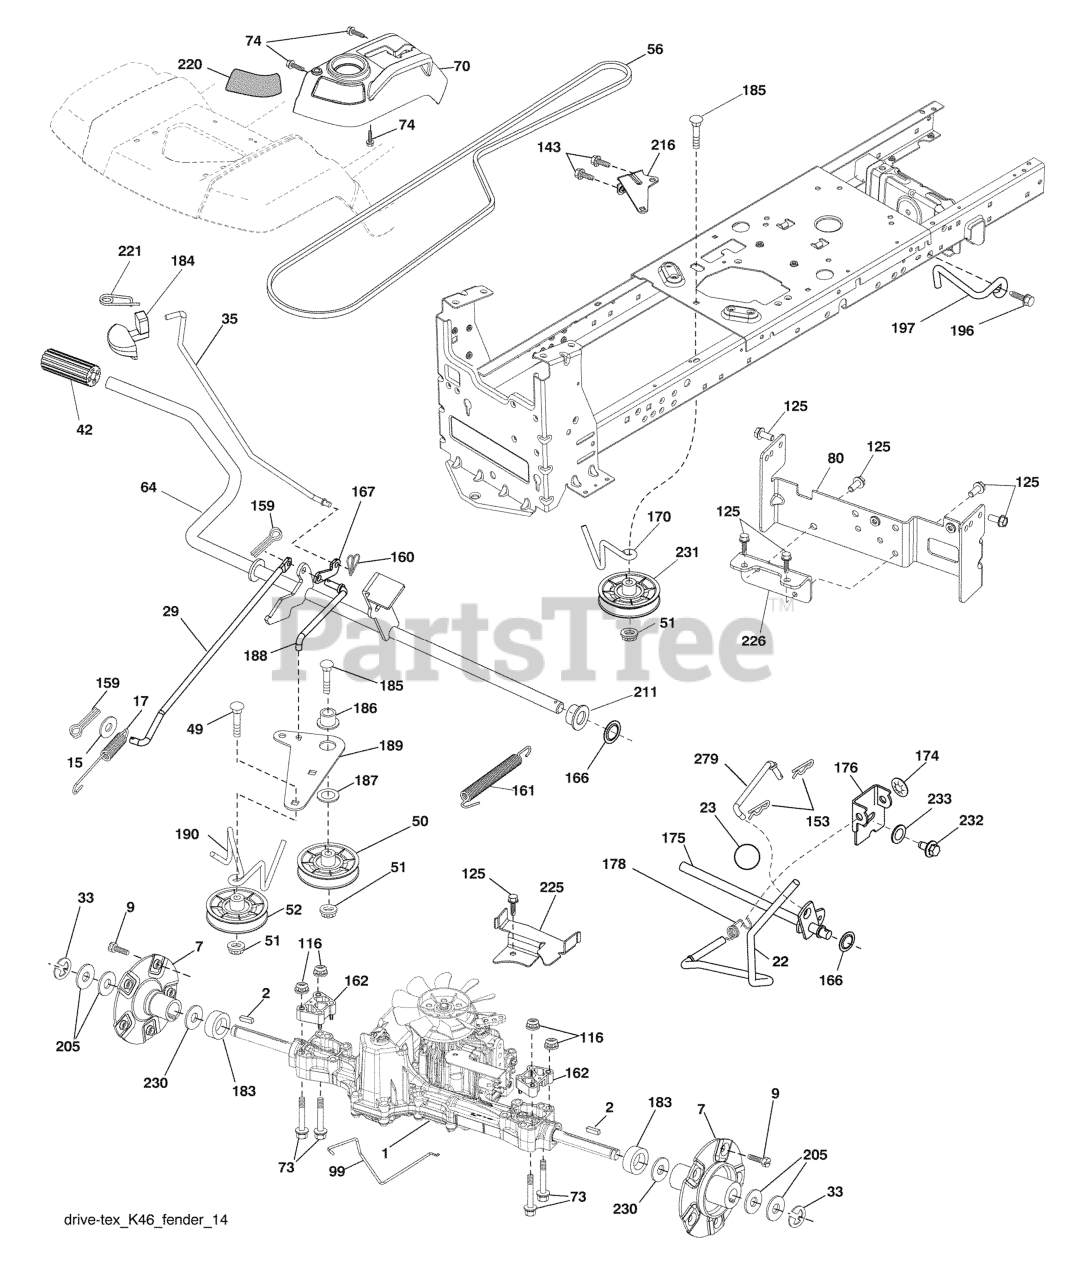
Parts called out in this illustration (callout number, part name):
1	TRANSAXLE(K46AW)22"FS
2	KEY.SQUARE.187X2.500
7	HUB.ASM.WHEEL.REAR.22"
9	HUB BOLT
15	WASHER
17	SPRING.BRAKE.K46.GREEN
22	ROD.SHIFT.FENDER.STGT.
23	KNOB.DELUXE.(PISTOL.GRIP).BLAC
29	ROD.BRAKE.K46
35	ROD.BRAKE.PARKING.GT.H
42	PEDAL COVER T
49	BOLT
50	IDLER.FLAT.910.OFFSET
51	NUT LOCK FLG 3/8-16 UNC
52	IDLER.V-GROOVE.910.OFFSET
56	V-BELT.MOWER.92.40.42/K46
64	SHAFT.ASM.PEDAL.BRAKE.
70	RP CONSOLE.ASM.HYDO.HUSQ.
73	BOLT.HEX.FLNG.5/16-18X3.75
74	SCREW.HI-LO.CONSOLE
80	STRAP TORQUE
99	ROD.SPRING.BYPASS.K46.TEX.GT
116	NUT LOCK HEX FLANGE 5/16-18
125	SCREW
143	Screw 5/16-18 x 1/2
153	RETAINER M
159	COTTER PIN
160	RETAINER CLIP
161	SPRING, RETURN LT
162	SPACER.TRANSAXLE.18&22
166	NUT.PUSH.625
167	LATCH.BRAKE.SPRING
170	KEEPER.CENTER SPAN.1.688
174	NUT.PUSH.500.2006
175	SHAFT ASM SHIFT
176	ARM.CLEVIS.ROD.SHIFT
178	SPRING.SHIFT.GT2006
183	SPACER.SPLIT.800X.350
184	HANDLE.PARKG.BRK.HUSQ X667
186	SPACER.RETAINER
187	WASHER 12/32X2X10GA
188	RP.LINK.CLUTCH.GROUND.DRIVE
189	BELLCRANK.GROUND.DRIVE.TEX.
190	KEEPER.BELLCRANK.DRIVE
196	SCREW 3/8-16X1
197	BRKT.ANIT-ROTATION.CLUTCH
211	BUSHING.SHAFT.BRAKE.HAND
216	BRACKET.PULLEY.IDLER.W/TEX
220	REFLECTOR.RH.TEX GT
221	RETAINER.SPRING.CLIP.H
225	KEEPER.BELT.TRANSAXLE.K46
226	BRKT.MOUNT.TORQUE.K46.
230	WASHER.HARDENED
231	IDLER.V-GROOVE.1.688.OFFSET
232	BOLT FIN HEX 7/16-14 X 1
233	WASHER SERRATED
279	LINK.SHIFT.T/A.K46.FEND.TX
